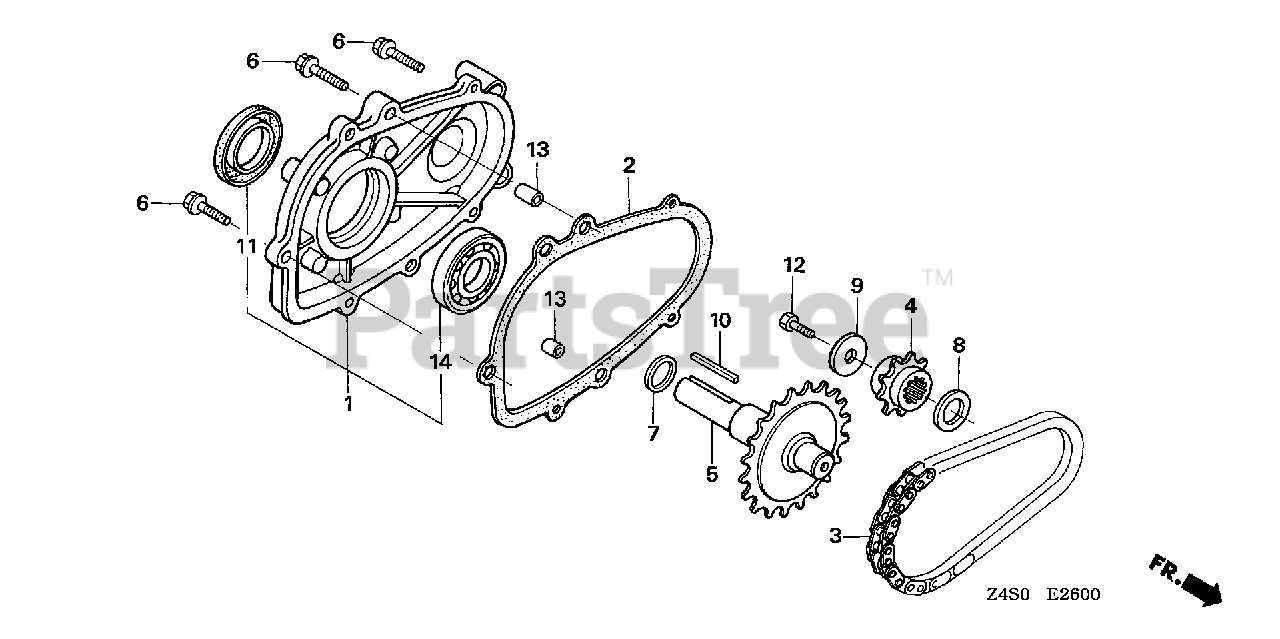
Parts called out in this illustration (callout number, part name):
1	COVER ASSY., CHAIN CASE
2	GASKET, CHAIN CASE COVER
3	CHAIN, P.T.O. DRIVE (DID317FM2-34LE)
4	SPROCKET, DRIVE (13T)
5	SHAFT, P.T.O. (26T)
6	BOLT, FLANGE (6X28) (CT200)
7	SPRING, THRUST
8	SPACER (20MM)
9	WASHER (8MM)
10	KEY (5X5X33) (YELLOW)
11	OIL SEAL (25X41X6) (NOK)
12	BOLT, HEX. (8X25)
13	PIN, DOWEL (8X14)
14	BEARING, RADIAL BALL (6205)
